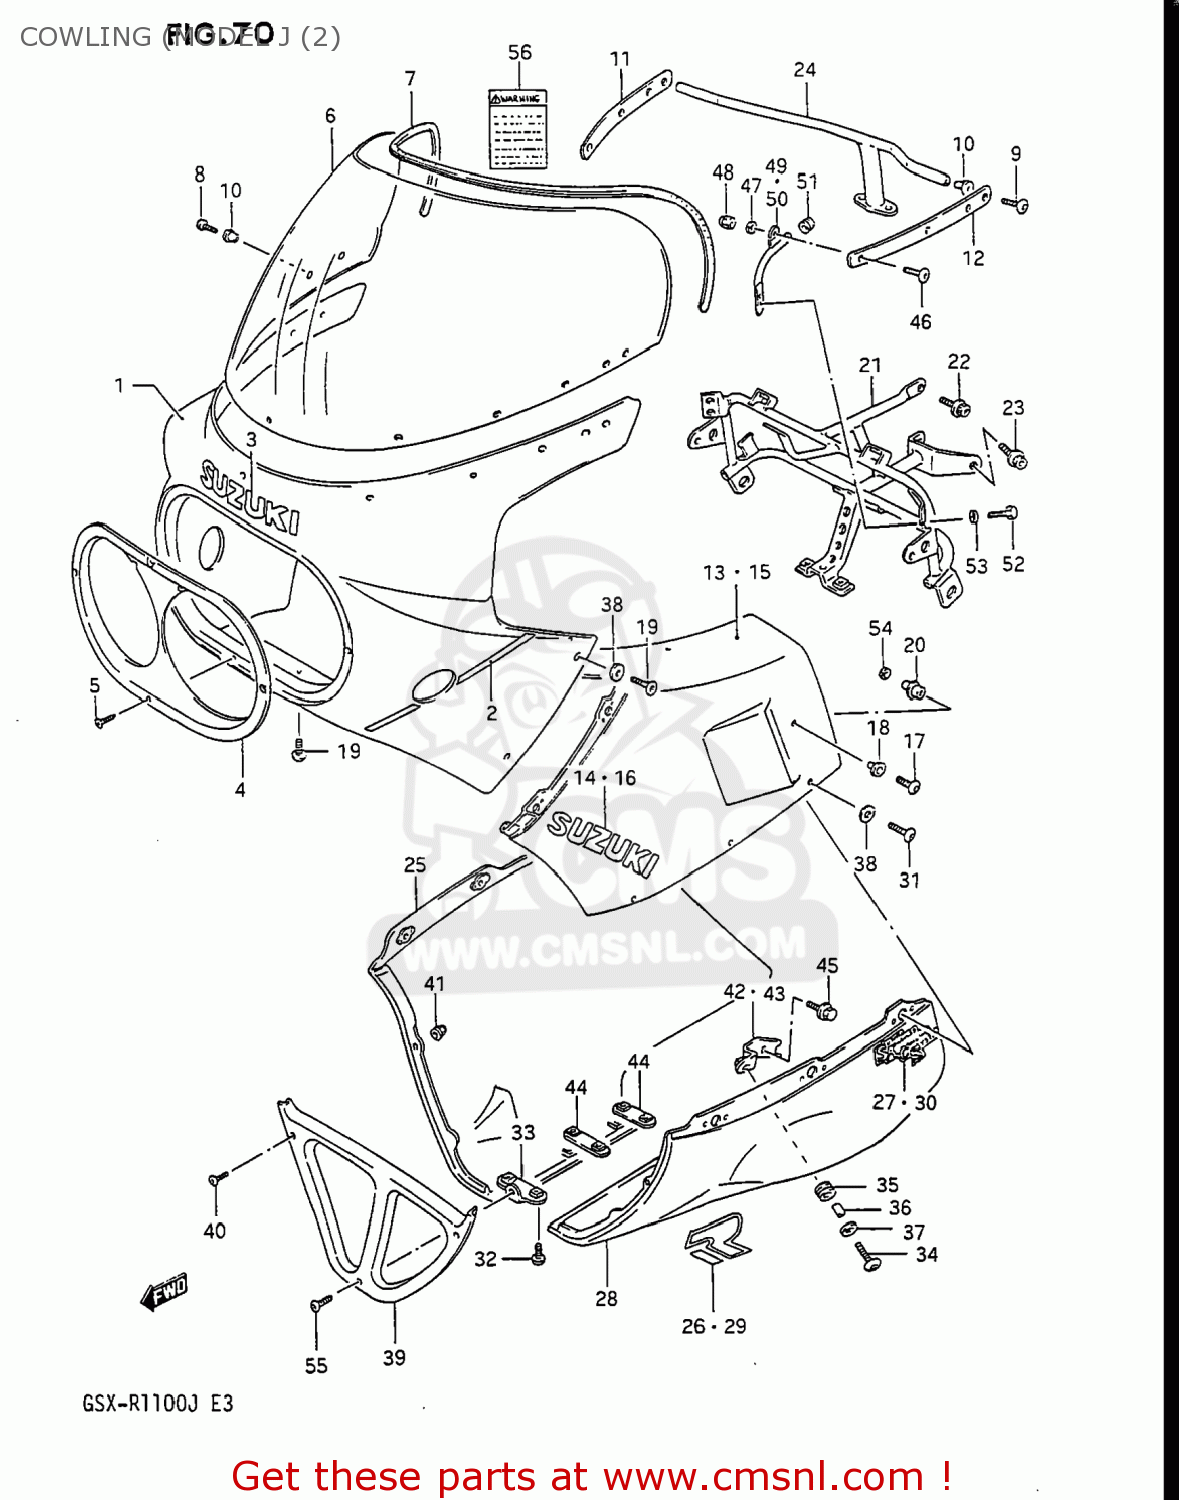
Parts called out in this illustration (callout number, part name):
1	BODY ASSEMBLY,COWLING
2	TAPE SET,COWLING,UPPER
3	EMBLEM,COWLING,UPPER (W)
4	COVER,COWLING,FRONT
5	SCREW
6	WINDSCREEN
7	MOLDING,SCREEN
8	SCREW(5X14)
9	SCREW(5X18)
10	NUT,COWLING SCREEN
11	PLATE,RR VIEW MIRROR,R
12	PLATE,RR VIEW MIRROR,L
13	COVER,COWLING SIDE,RIGHT
14	EMBLEM
15	COVER,COWLING SIDE,LEFT
16	EMBLEM
17	SCREW(6X12)
18	WASHER
19	SCREW(6X16)
20	CUSHION,COWLING
21	BRACE,COWLING FR
22	BOLT
23	BOLT
24	BRACE,COWLING BODY RR
25	COVER,COWLING,LOWER,RIGHT
26	EMBLEM,COWLING UNDER
27	EMBLEM,COWLING,UNDER
28	COVER,COWLING,LOWER,LEFT
29	EMBLEM,COWLING UNDER
30	EMBLEM,COWLING,UNDER
31	SCREW(6X16)
32	SCREW(6X16)
33	BRACE,COWLING LWR COVER
34	SCREW(6X20)
35	CUSHION
36	SPACER
37	WASHER(6.5X18X1)
38	WASHER
39	COVER,COWLING,LOWER,FRONT
40	SCREW(5X14)
41	NUT
42	BRACE,COWLING LWR,R
43	BRACE,COWLING LWR,L
44	BRACE,COWLING LWR COVER RR
45	BOLT
46	SCREW(6X16)
47	WASHER,LOCK
48	NUT 6MM
49	BRACE,MIRROR,R
50	BRACE,MIRROR,L
51	PLUG(OD:12)
52	BOLT 6X16
53	WASHER,LOCK
54	WASHER
55	SCREW(6X16)
56	LABEL (WARNING SCREEN)
